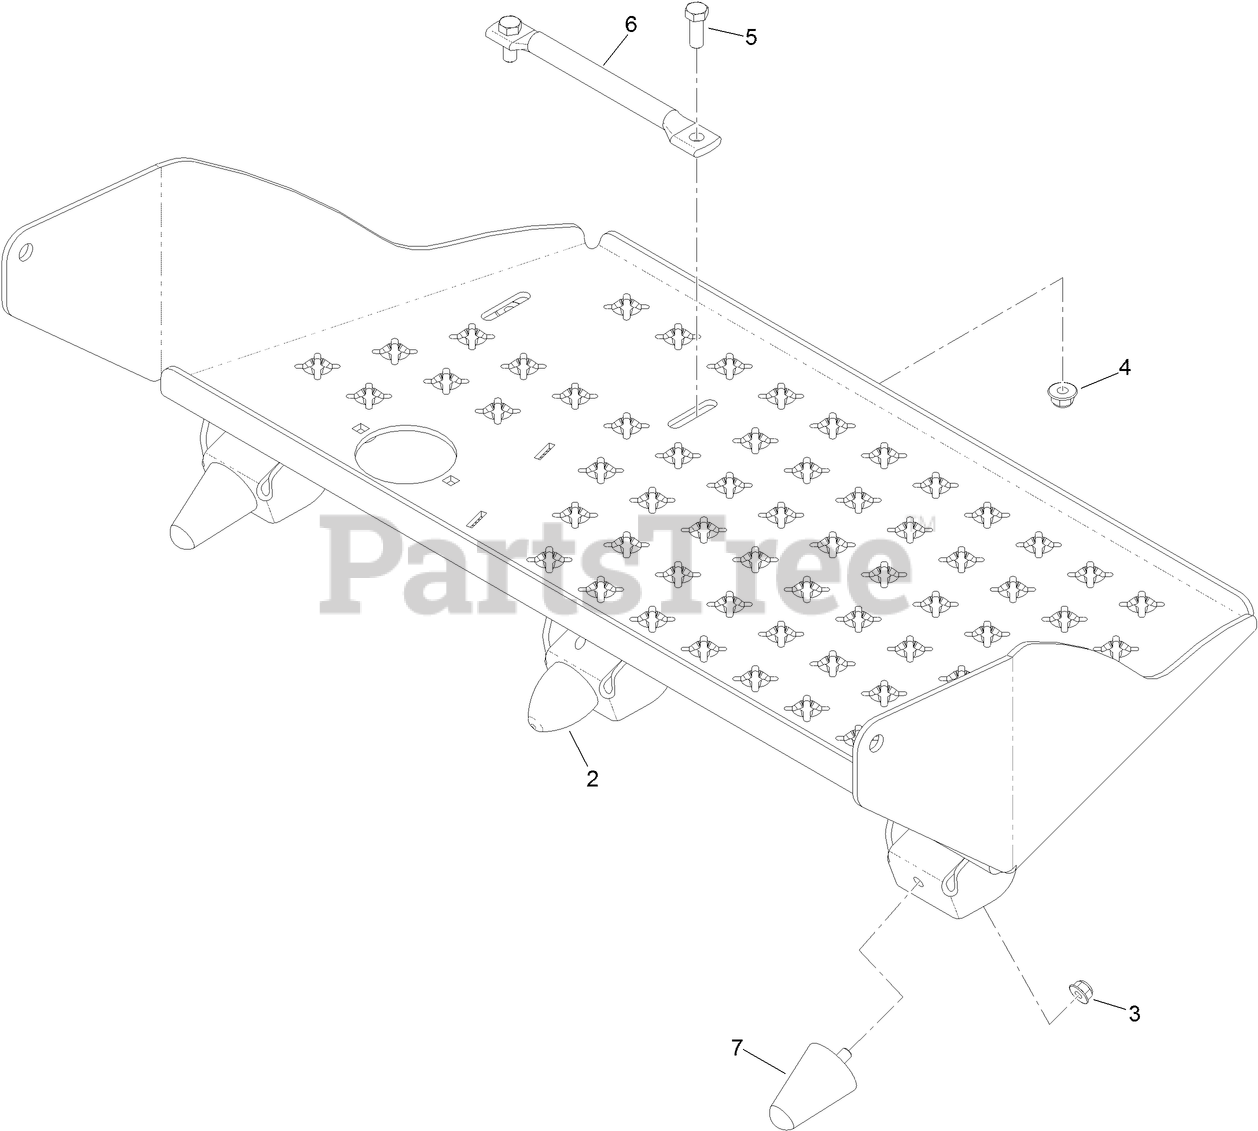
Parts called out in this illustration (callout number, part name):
2	BUMPER-RUBBER
3	NUT-HF, NI
4	NUT-HF, NI
5	SCREW-HH
6	ROCKER-PEDAL, FOOT
7	BUMPER-RUBBER
